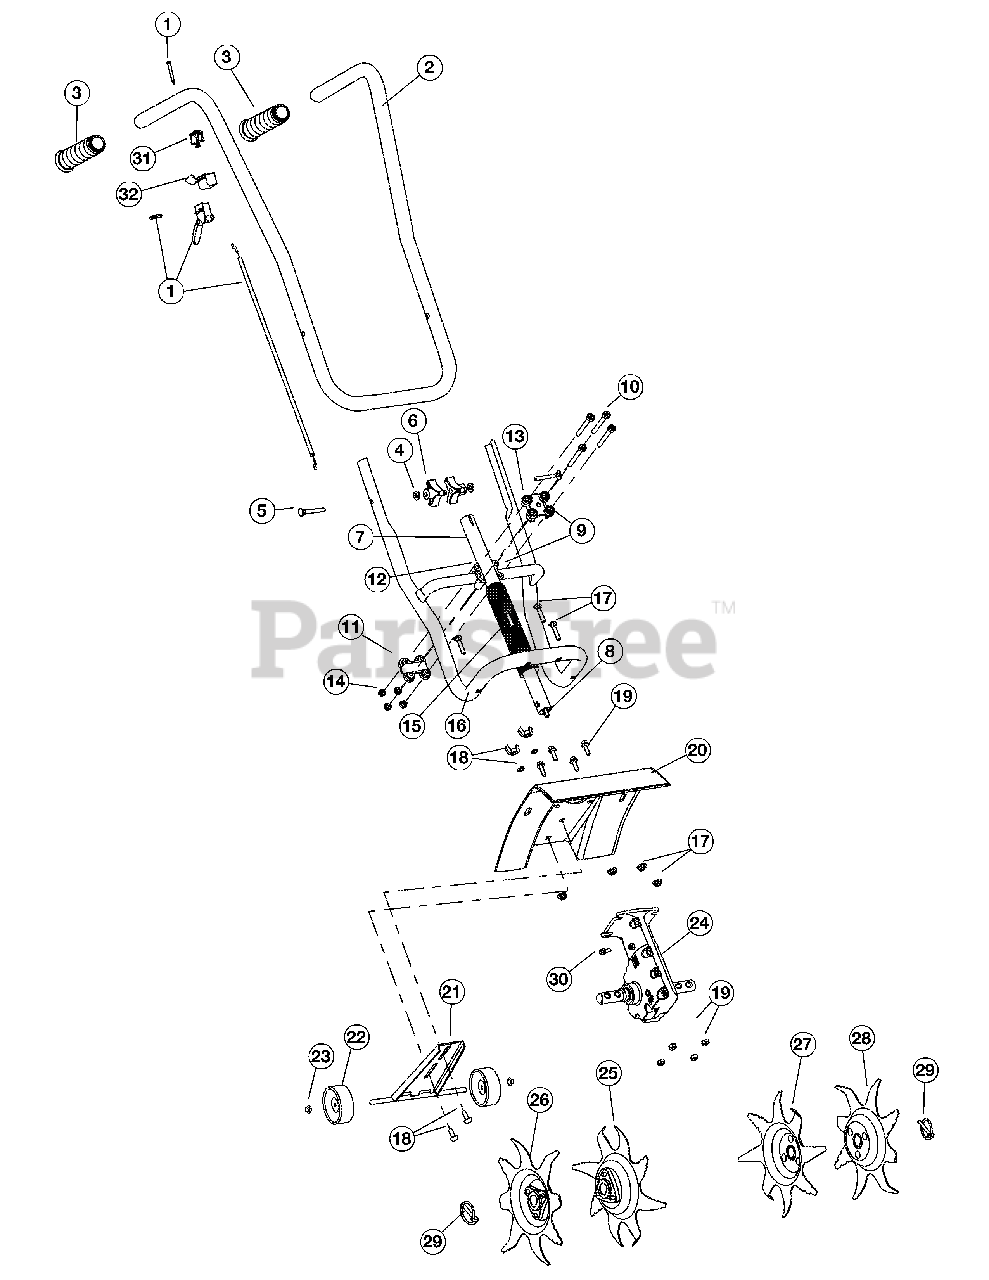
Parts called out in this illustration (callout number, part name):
1	Throttle Trigger and Cable Assembly
2	Handle Bar Assembliy, Upper (includes 3)
4	Washer
6	Knob, 3 prong
7	Drive Shaft Housing Assembly
8	Flexible Drive Shaft
9	Handle Bracket Assembly (includes 11-15)
11	Upper Handle Clamp
12	Middle Handle Clamp
13	Lower Handle Clamp
16	Lower Handle Bar
17	Hardware, Handle Bar Mounting (lower)
18	Wheel Bracket Mounting Hardware
19	Guard Mounting Hardware
21	Wheel Bracket Assembly
22	Wheel (includes 23)
23	Wheel Cap
24	Gearbox Assembly
25	Inner Tine (right side)
26	Outer Tine (right side)
27	Inner Tine (left side)
28	Outer Tine (left side)
29	Click Pin
30	Sleeve Retainer Bolt
32	Bracket
